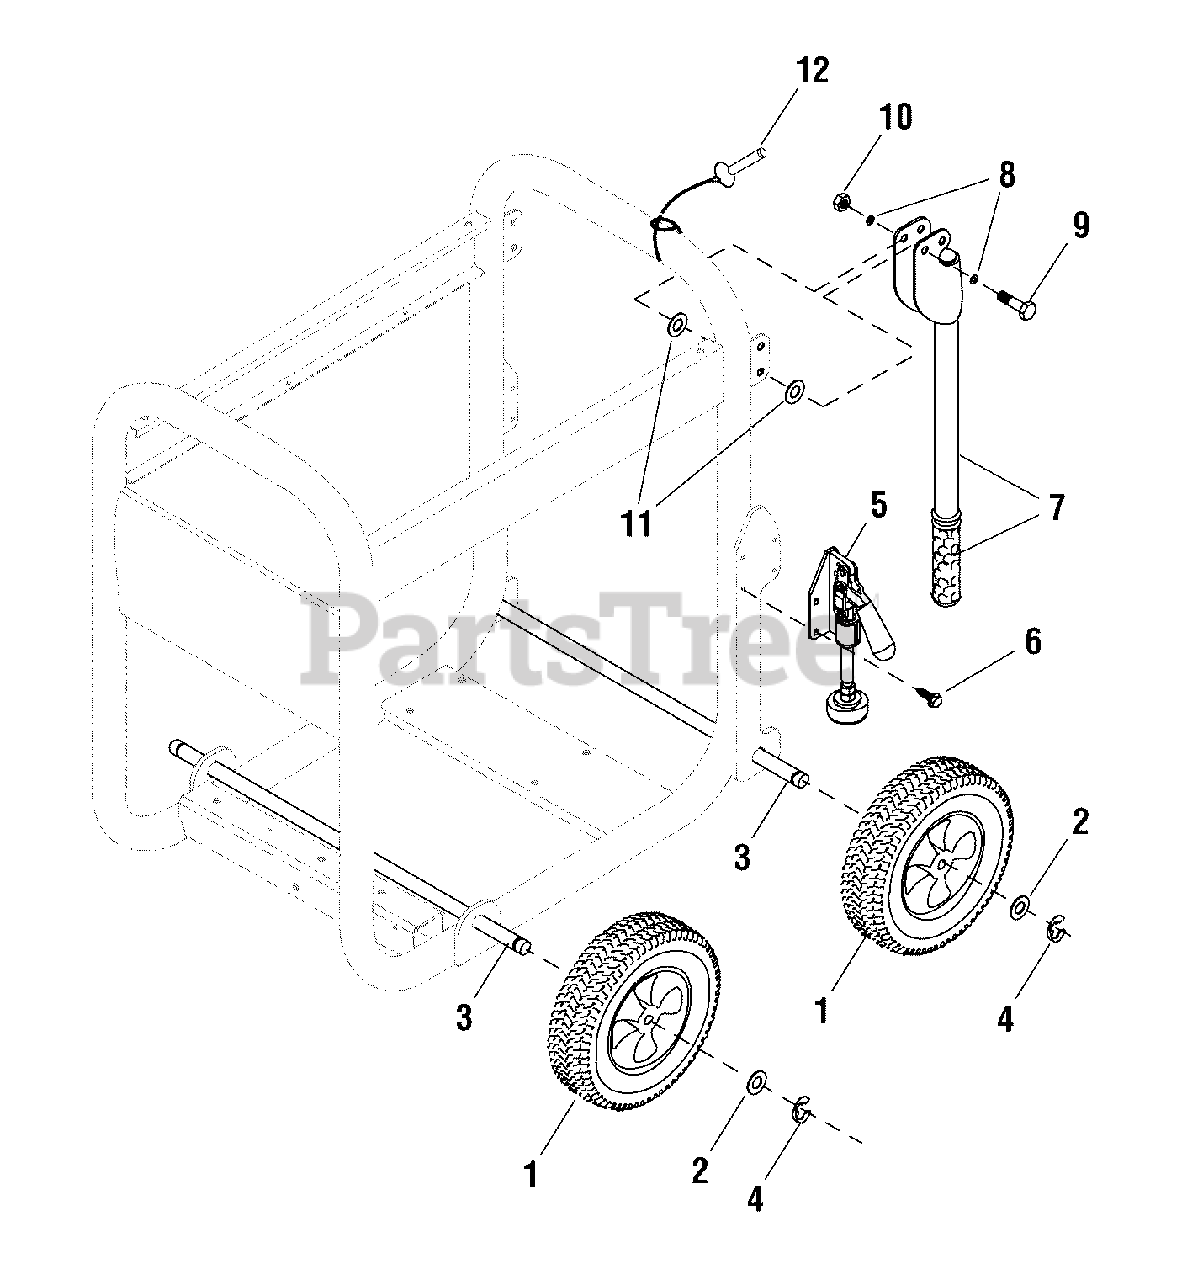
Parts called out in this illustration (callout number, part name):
2	* WASHER, 5/8
4	E-RING
6	* SCREW, 1/4-20 x 3/8
8	* WASHER, Flat, 5/16 - M8
9	* NUT, Nylock, M8-1.25
10	* CAPSCREW, Hex Head, M8-1.25 x 45
11	* WASHER, Flat, Nylon
